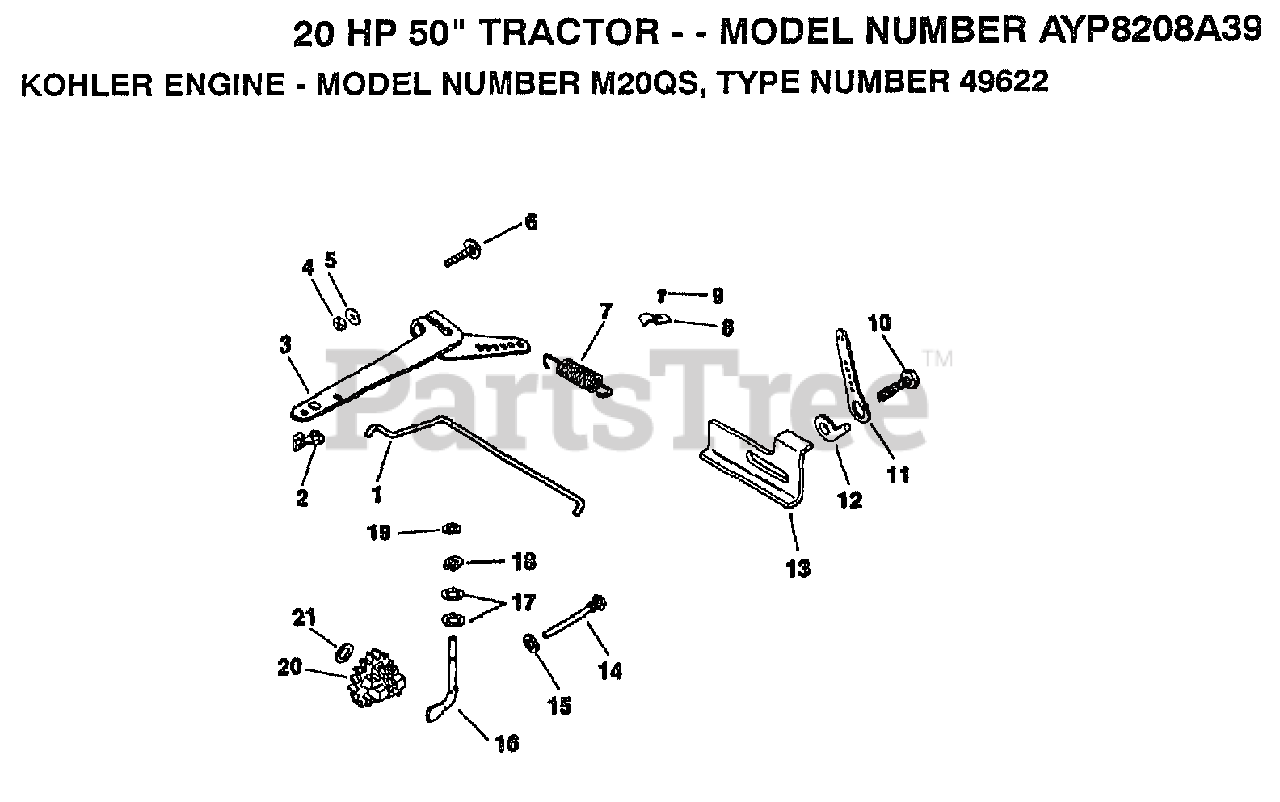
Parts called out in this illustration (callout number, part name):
1	KIT, GOVERNOR LINKAGE
3	ARM, GOVERNOR
7	SPRING, GOVERNOR
11	LEVER, SPEED CONTROL
12	STOP, GOVERNOR
13	STOP, HIGH SPEED
16	PIN, GOVERNOR STOP
19	WASHER, PLAIN 1/4
